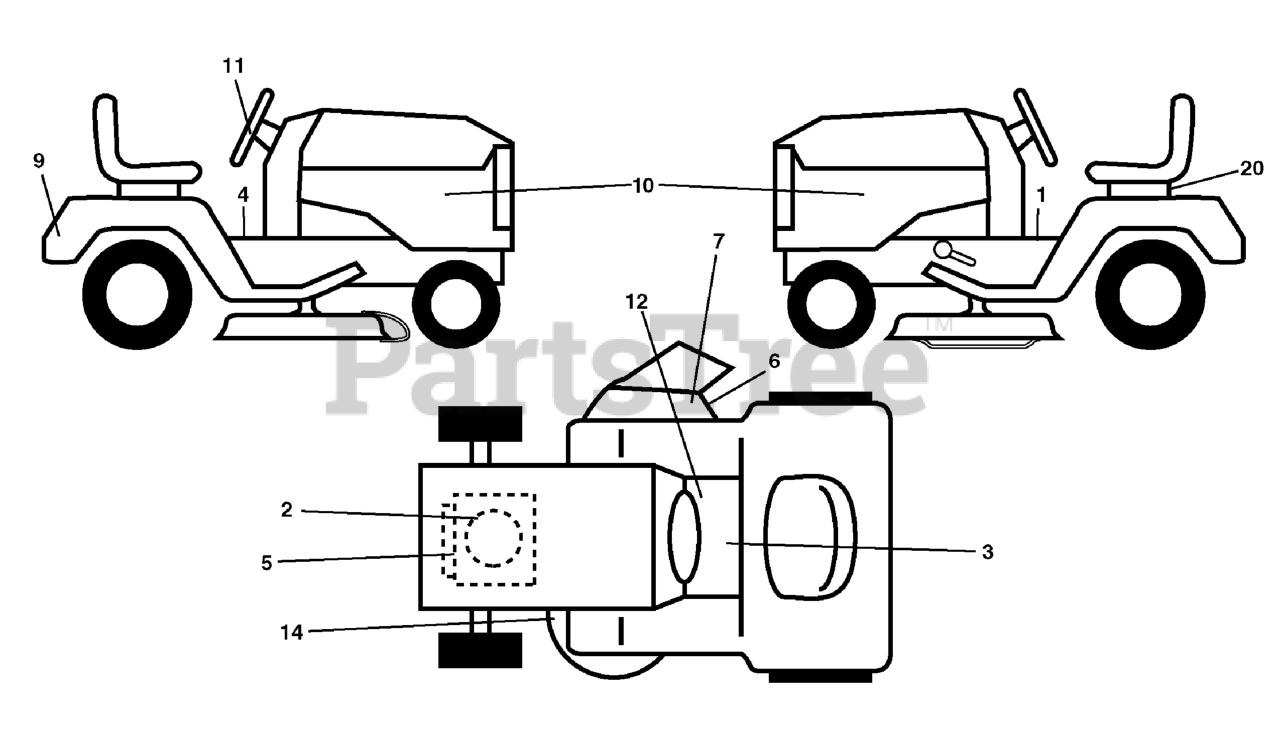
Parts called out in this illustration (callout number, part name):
1	Decal Brake/Clutch Symbol
2	Decal Engine H.P.
3	Decal Warning Symbols
4	Decal Saddle Brake Parking
5	Decal Warning Engine
6	Decal Warning, Keep Hand Away
7	Decal Deflect WRN. Cutfinger
9	Decal Fender Logo
10	Decal Sidepanel
11	Decal Ins Strg Whl
12	Decal Operator Cruise
14	Decal V-Belt Schematic
